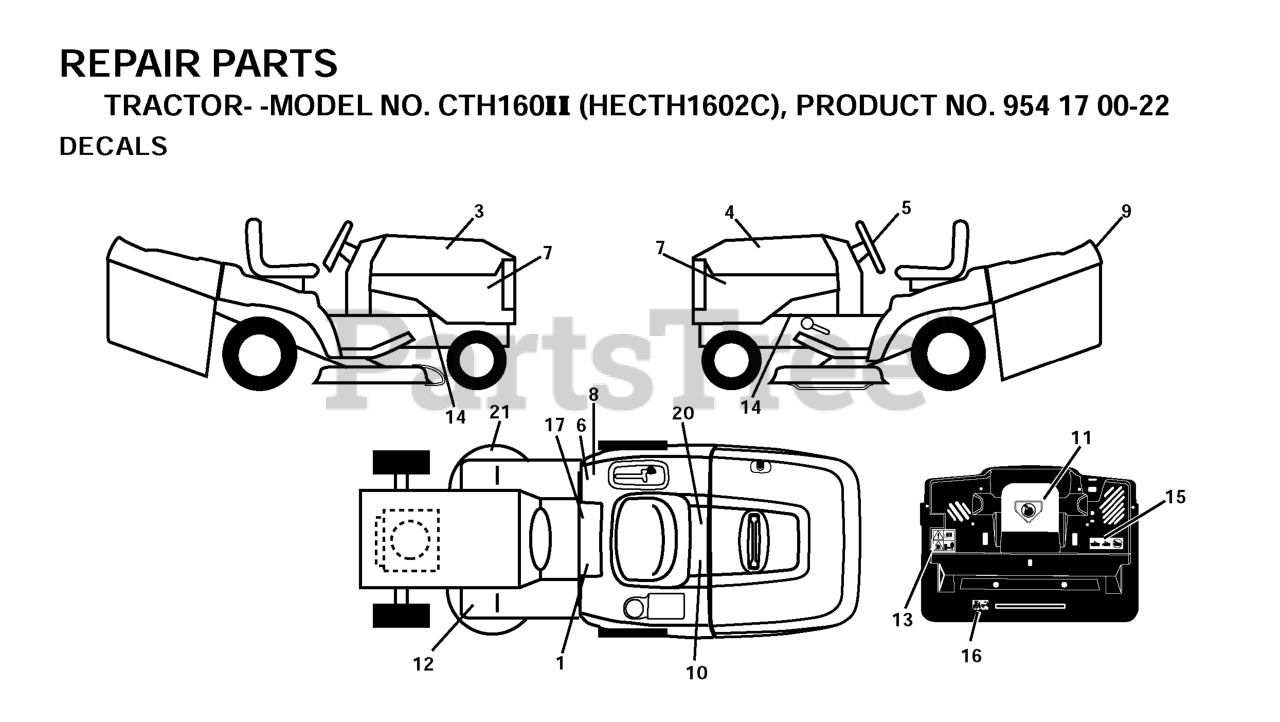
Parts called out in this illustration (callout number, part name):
1	DECAL READ OWNER'S MAN SYMS
5	DECAL.WHEEL.STEERING.HUSQ.PERM
6	DECAL CERTIFICATION
7	DECAL PNL SIDE
8	DECAL EUROPE STANDARD CE
9	DECAL FENDER HUSQ
10	DECAL BTRY SYMBOLS
11	DECAL MOWER CUT/FINGER
12	DECAL
13	Decal Warn Back Plate CRD
16	DECAL
17	DECAL PARK BRAKE
20	DECAL.BYPASS.FENDER.CRD.LT.YT
